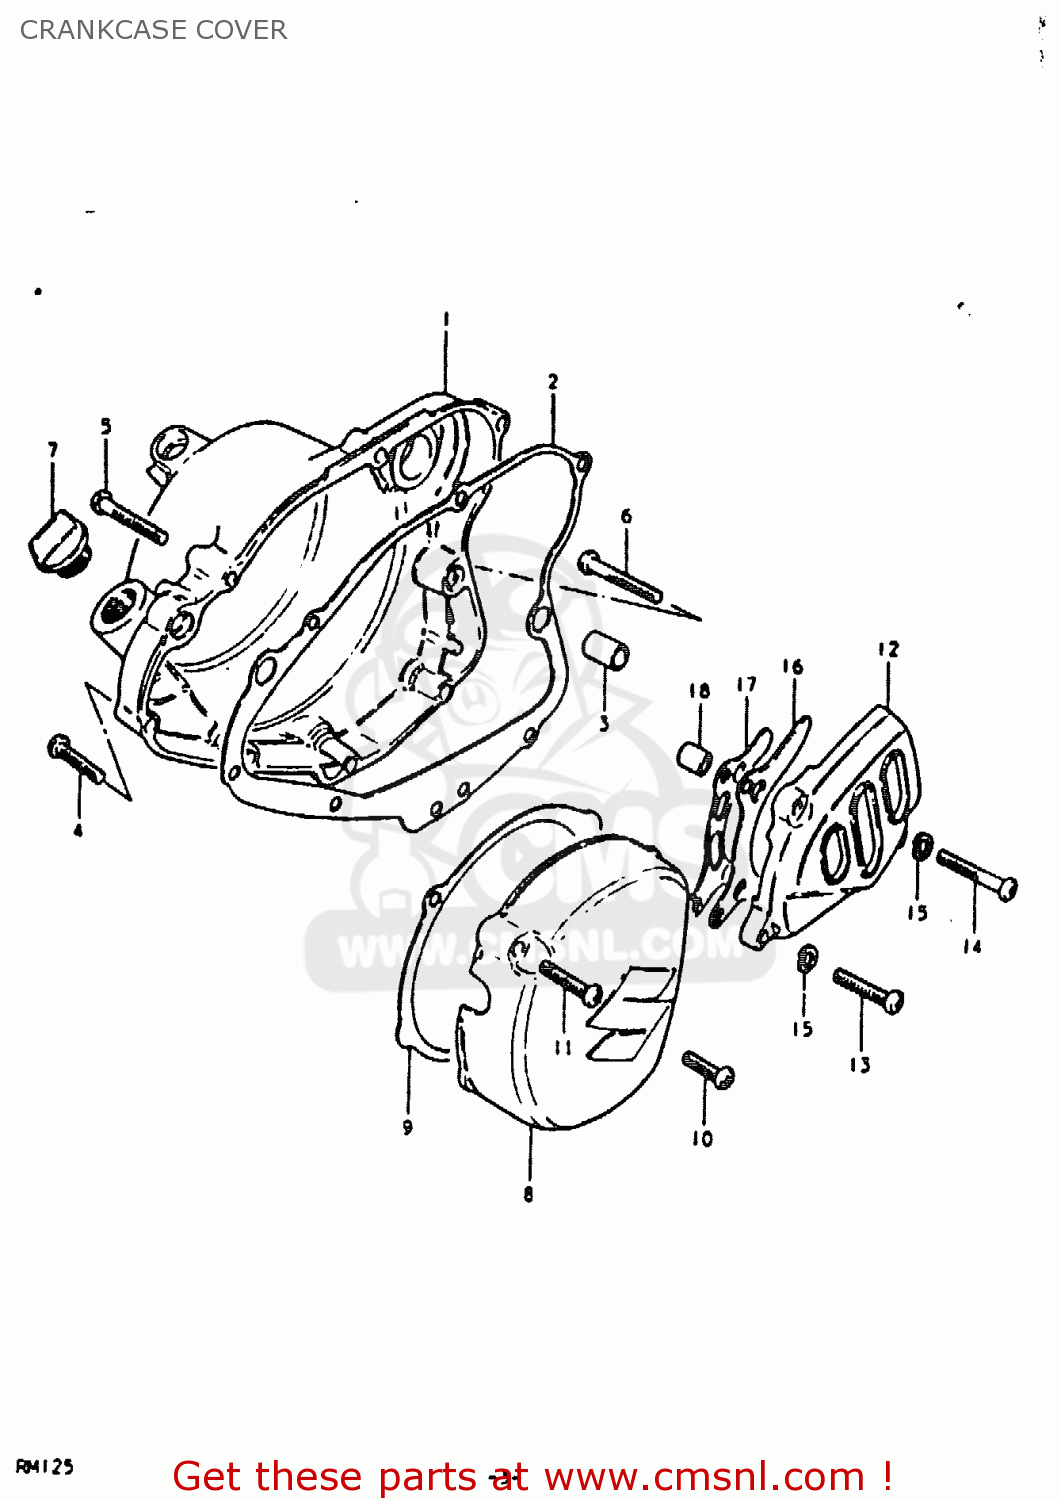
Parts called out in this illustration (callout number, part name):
1	COVER,CLUTCH
2	GASKET,CLUTCH COVER (MCA)
3	PIN
4	SCREW 6X30
5	SCREW
6	SCREW (6X45)
7	PLUG,OIL FILTER
8	COVER
9	GASKET,MAGNETO COVER (MCA)
10	SCREW
11	SCREW 6X30
12	COVER,ENGINE SPROCKET
13	BOLT 6X35
14	SCREW (6X45)
15	LOCK WASHER
16	PLATE,CHAIN FRONT GUIDE
18	SPACER(6.5X10.5X12)
